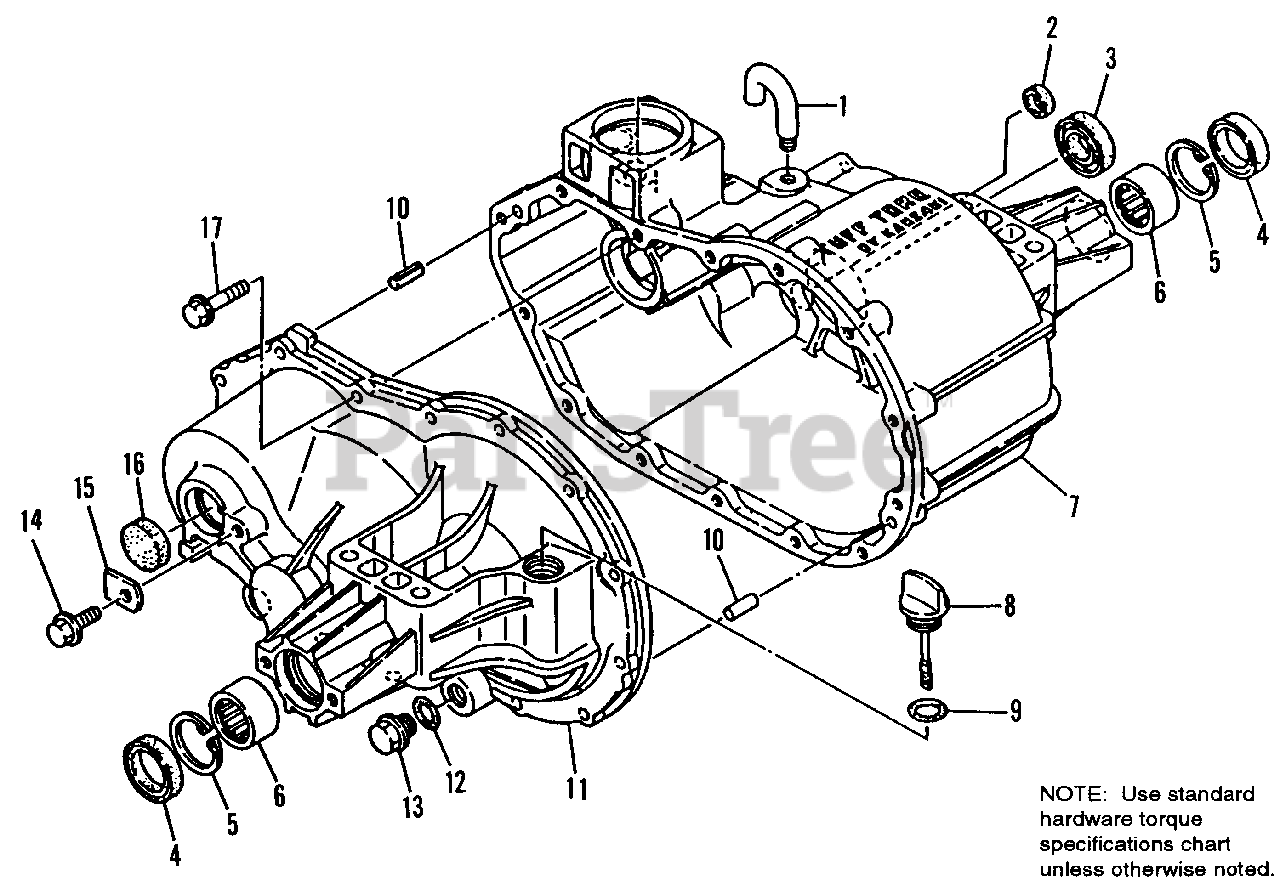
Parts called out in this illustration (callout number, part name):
5	RING, Internal Snap
6	BEARING, Needle
7	HOUSING, Transmission, R.H.
11	HOUSING, Transmission, L.H.
14	SCREW, Self Threading
16	CAP, Sealing
